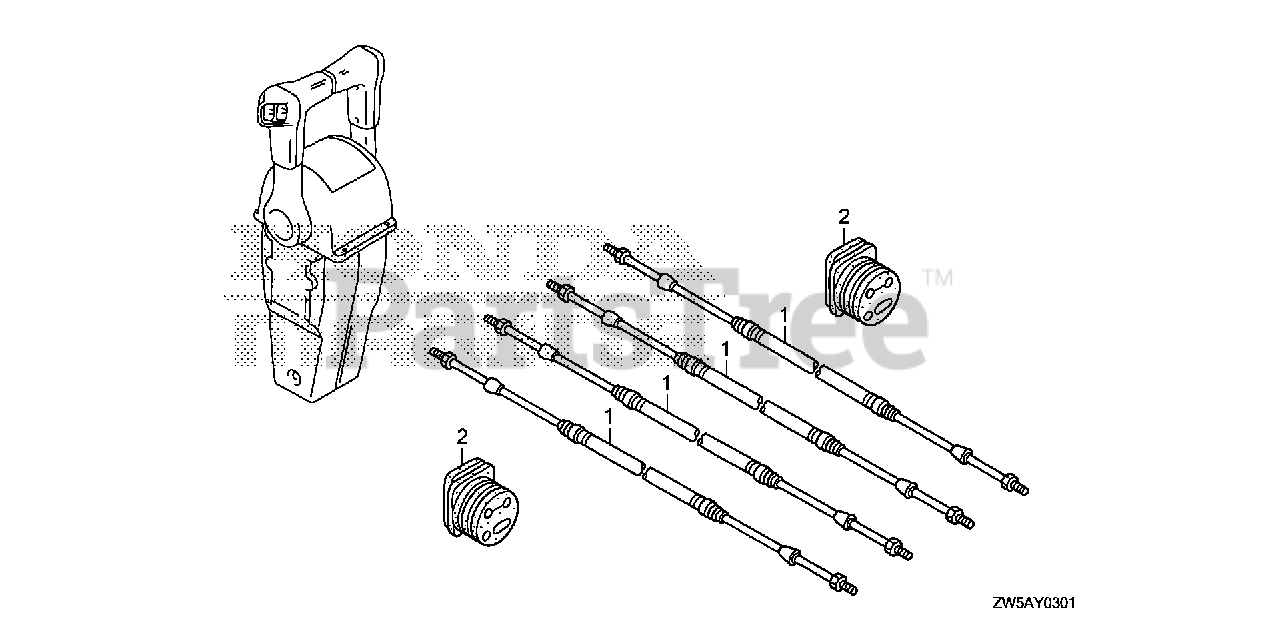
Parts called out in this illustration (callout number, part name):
1	CABLE, REMOTE CONTROL (10') (LOW FRICTION)
1	CABLE ASSY., PUSH-PULL (33C-5FT)
1	CABLE, REMOTE CONTROL (11') (LOW FRICTION)
1	CABLE ASSY., PUSH-PULL (33C-6FT)
1	CABLE, REMOTE CONTROL (12') (LOW FRICTION)
1	CABLE ASSY., PUSH-PULL (33C-7FT)
1	CABLE, REMOTE CONTROL (13') (LOW FRICTION)
1	CABLE ASSY., PUSH-PULL (33C-8FT)
1	CABLE, REMOTE CONTROL (14') (LOW FRICTION)
1	CABLE ASSY., PUSH-PULL (33C-9FT)
1	CABLE, REMOTE CONTROL (15') (LOW FRICTION)
1	CABLE ASSY., PUSH-PULL (33C-10FT)
1	CABLE, REMOTE CONTROL (16') (LOW FRICTION) (NOT AVAILABLE)
1	CABLE ASSY., PUSH-PULL (33C-11FT)
1	CABLE, REMOTE CONTROL (17') (LOW FRICTION)
1	CABLE ASSY., PUSH-PULL (33C-12FT)
1	CABLE, REMOTE CONTROL (18') (LOW FRICTION) (NOT AVAILABLE)
1	CABLE ASSY., PUSH-PULL (33C-13FT)
1	CABLE, REMOTE CONTROL (19') (LOW FRICTION)
1	CABLE ASSY., PUSH-PULL (33C-14FT)
1	CABLE, REMOTE CONTROL (20') (LOW FRICTION) (NOT AVAILABLE)
1	CABLE ASSY., PUSH-PULL (33C-15FT)
1	CABLE, REMOTE CONTROL (21') (LOW FRICTION)
1	CABLE ASSY., PUSH-PULL (33C-16FT)
1	CABLE, REMOTE CONTROL (22') (LOW FRICTION) (NOT AVAILABLE)
1	CABLE ASSY., PUSH-PULL (33C-17FT)
1	CABLE, REMOTE CONTROL (23') (LOW FRICTION)
1	CABLE ASSY., PUSH-PULL (33C-18FT)
1	CABLE, REMOTE CONTROL (24') (LOW FRICTION) (NOT AVAILABLE)
1	CABLE ASSY., PUSH-PULL (33C-19FT)
1	CABLE, REMOTE CONTROL (25') (LOW FRICTION)
1	CABLE ASSY., PUSH-PULL (33C-20FT)
1	CABLE, REMOTE CONTROL (26') (LOW FRICTION)
1	CABLE ASSY., PUSH-PULL (33C-21FT)
1	CABLE, REMOTE CONTROL (27') (LOW FRICTION)
1	CABLE ASSY., PUSH-PULL (33C-22FT)
1	CABLE, REMOTE CONTROL (28') (LOW FRICTION) (NOT AVAILABLE)
1	CABLE ASSY., PUSH-PULL (33C-23FT)
1	CABLE, REMOTE CONTROL (29') (LOW FRICTION)
1	CABLE ASSY., PUSH-PULL (33C-24FT)
1	CABLE, REMOTE CONTROL (30') (LOW FRICTION) (NOT AVAILABLE)
1	CABLE ASSY., PUSH-PULL (33C-25FT)
1	CABLE, REMOTE CONTROL (31') (LOW FRICTION)
1	CABLE ASSY., PUSH-PULL (33C-26FT)
1	CABLE, REMOTE CONTROL (32') (LOW FRICTION) (NOT AVAILABLE)
1	CABLE ASSY., PUSH-PULL (33C-27FT)
1	CABLE, REMOTE CONTROL (33') (LOW FRICTION)
1	CABLE ASSY., PUSH-PULL (33C-28FT)
1	CABLE, REMOTE CONTROL (34') (LOW FRICTION) (NOT AVAILABLE)
1	CABLE ASSY., PUSH-PULL (33C-29FT)
1	CABLE, REMOTE CONTROL (35') (LOW FRICTION)
1	CABLE ASSY., PUSH-PULL (33C-30FT)
1	CABLE ASSY., PUSH-PULL (33C-31FT)
1	CABLE ASSY., PUSH-PULL (33C-32FT)
2	GROMMET, CASE (LOWER) (B)
